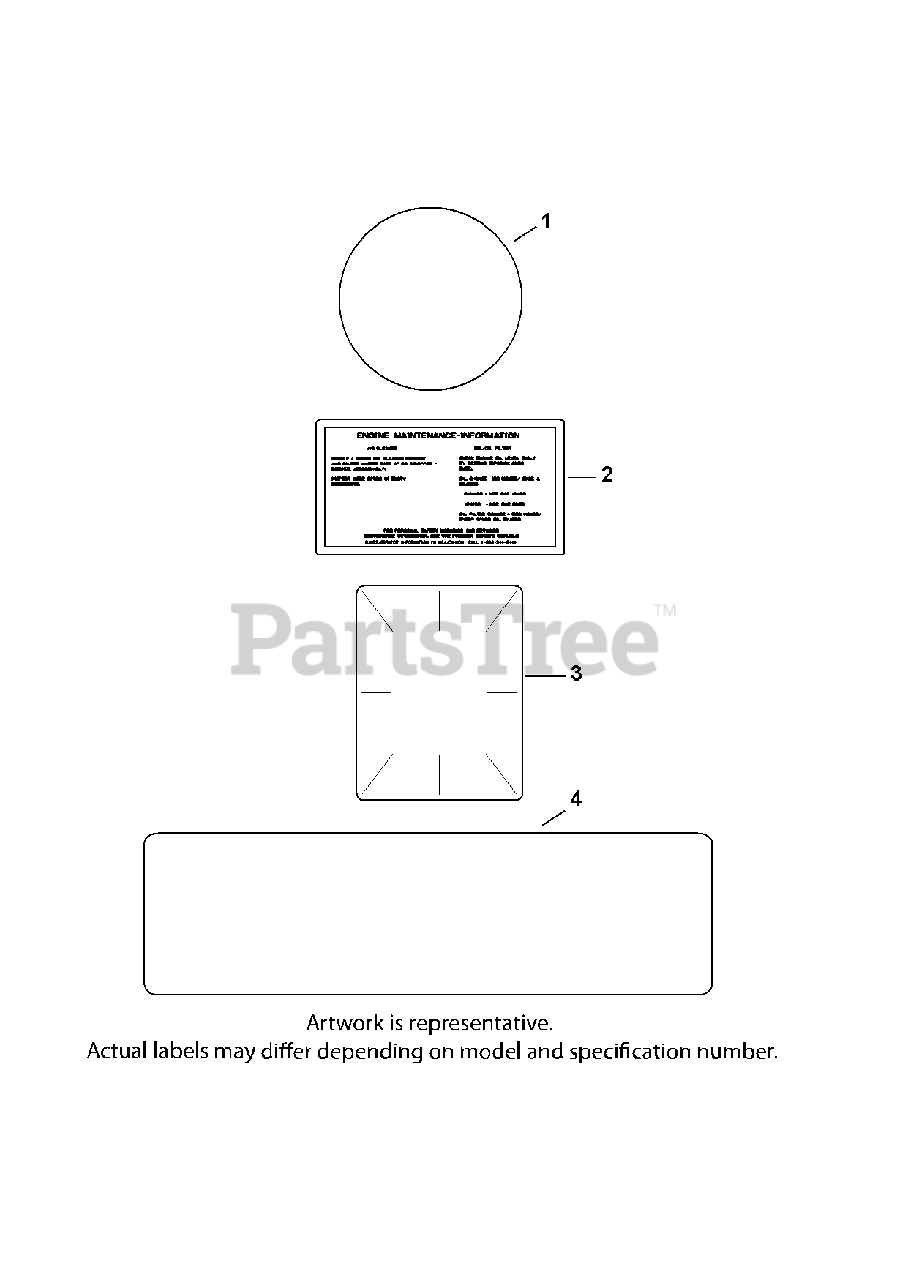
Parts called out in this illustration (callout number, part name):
1	Decal, Grass Screen
2	Decal, Air Cleaner
3	Decal, Clear Laminate
